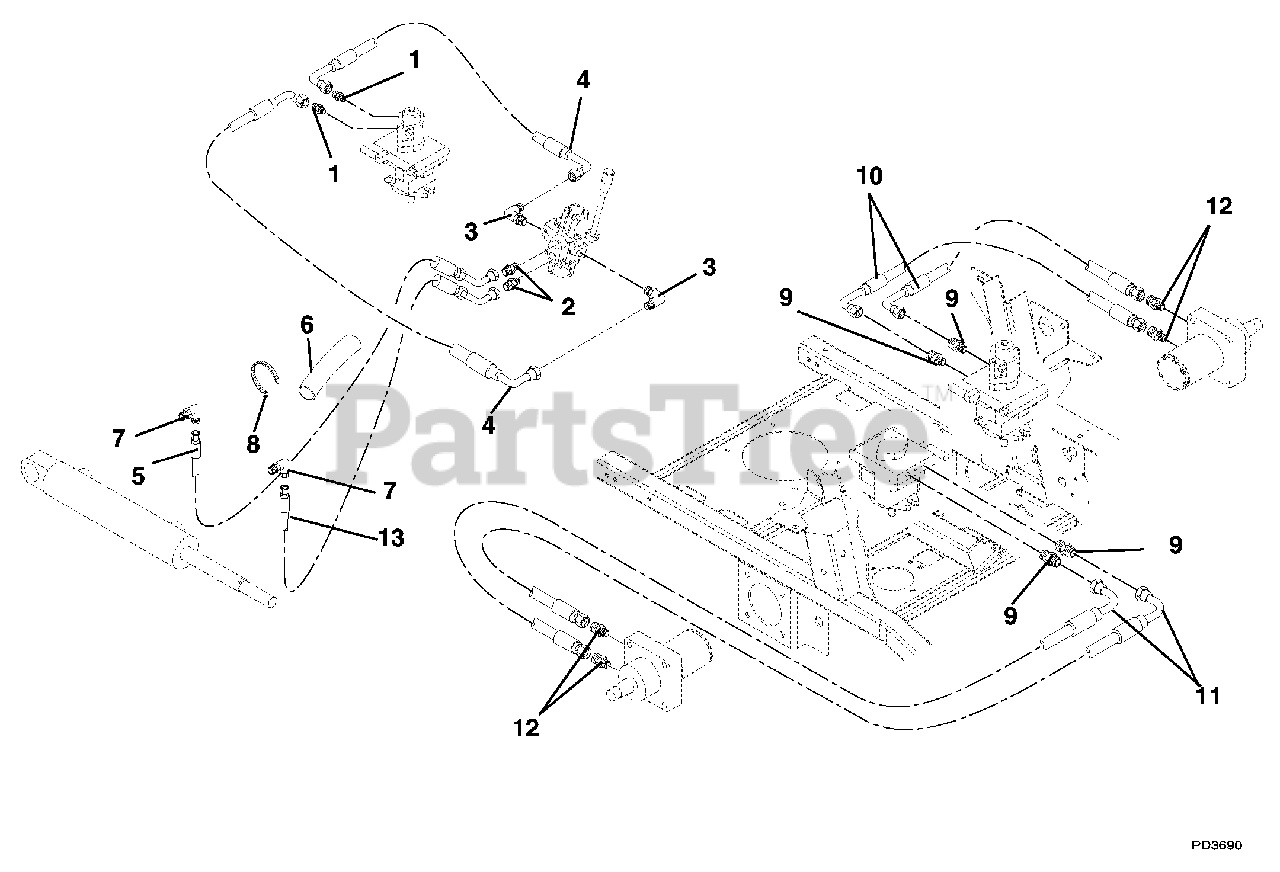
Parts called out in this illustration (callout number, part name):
1	Fitting, Hydraulic
2	Fitting, Hydraulic
3	Fitting, Hydraulic Elbow
4	Hose, Hydraulic
5	Hose, Hydraulic
6	Sleeve, Protective 24"
7	Fitting, Hydraulic Elbow
8	Cable Tie
9	Adapter, Hydraulic
10	Hose, Hydraulic
11	Hose, Hydraulic
12	Adapter, Hydraulic
13	Hose, Hydraulic
